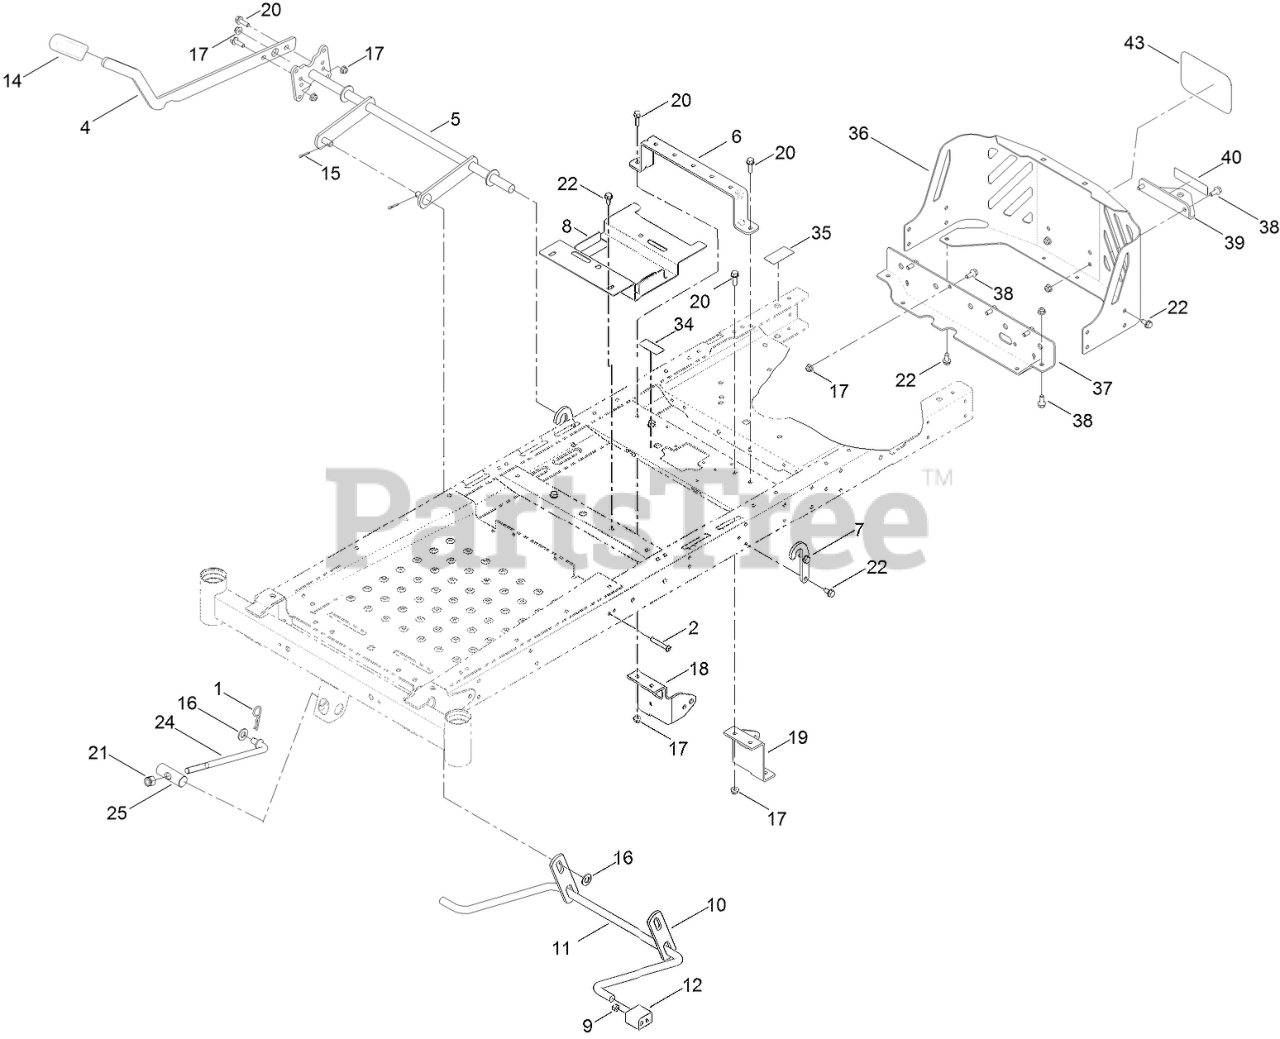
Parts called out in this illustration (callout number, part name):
1	PIN-COTTER
2	SCREW-HSBH
4	LEVER-LIFT
5	LIFT-DECK, NARROW
6	BRACE-SEAT, REAR (NARROW)
7	BRACKET-LIFT
8	BRACKET-BATTERY
9	NUT-LOCK, NI
10	LINK-LIFT
11	ARM-LIFT, REAR
12	BLOCK-PIVOT
14	GRIP-LEVER
15	PIN-COTTER
16	WASHER-FLAT
17	NUT-HF, NI
18	MOUNT-HYDRO, FRONT (RH)
19	MOUNT-HYDRO, FRONT (LH)
20	SCREW-HHF
21	NUT-HEX
22	SCREW-HWHTF
24	ROD-MOUNT, DECK
25	PIN-PIVOT
34	DECAL-LOCATION, SERVICE DEALER
35	DECAL-BYPASS
36	GUARD-ENGINE, NARROW
37	CROSSMEMBER-REAR, NARROW
38	SCREW-HHF
39	BRACKET-HITCH
43	DECAL
